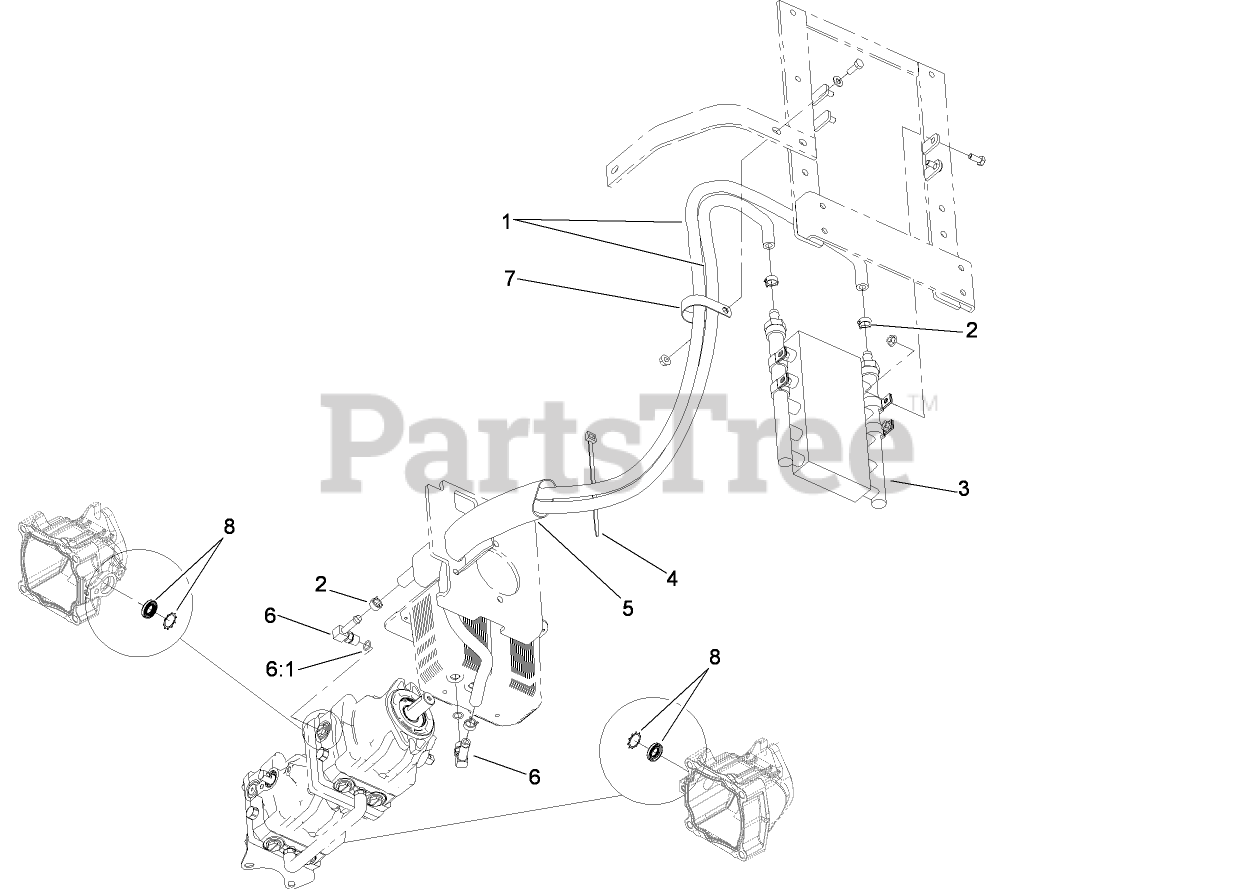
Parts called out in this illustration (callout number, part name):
1	HOSE-HYDRAULIC
2	CLAMP-HOSE
3	COOLER-OIL, HYDRO
4	TIE-PLASTIC
5	SLEEVE-FABRIC
6	FITTING-ELBOW, 90
6:1	O-RING
7	CLAMP-R
8	TRUNNION SEAL KIT
